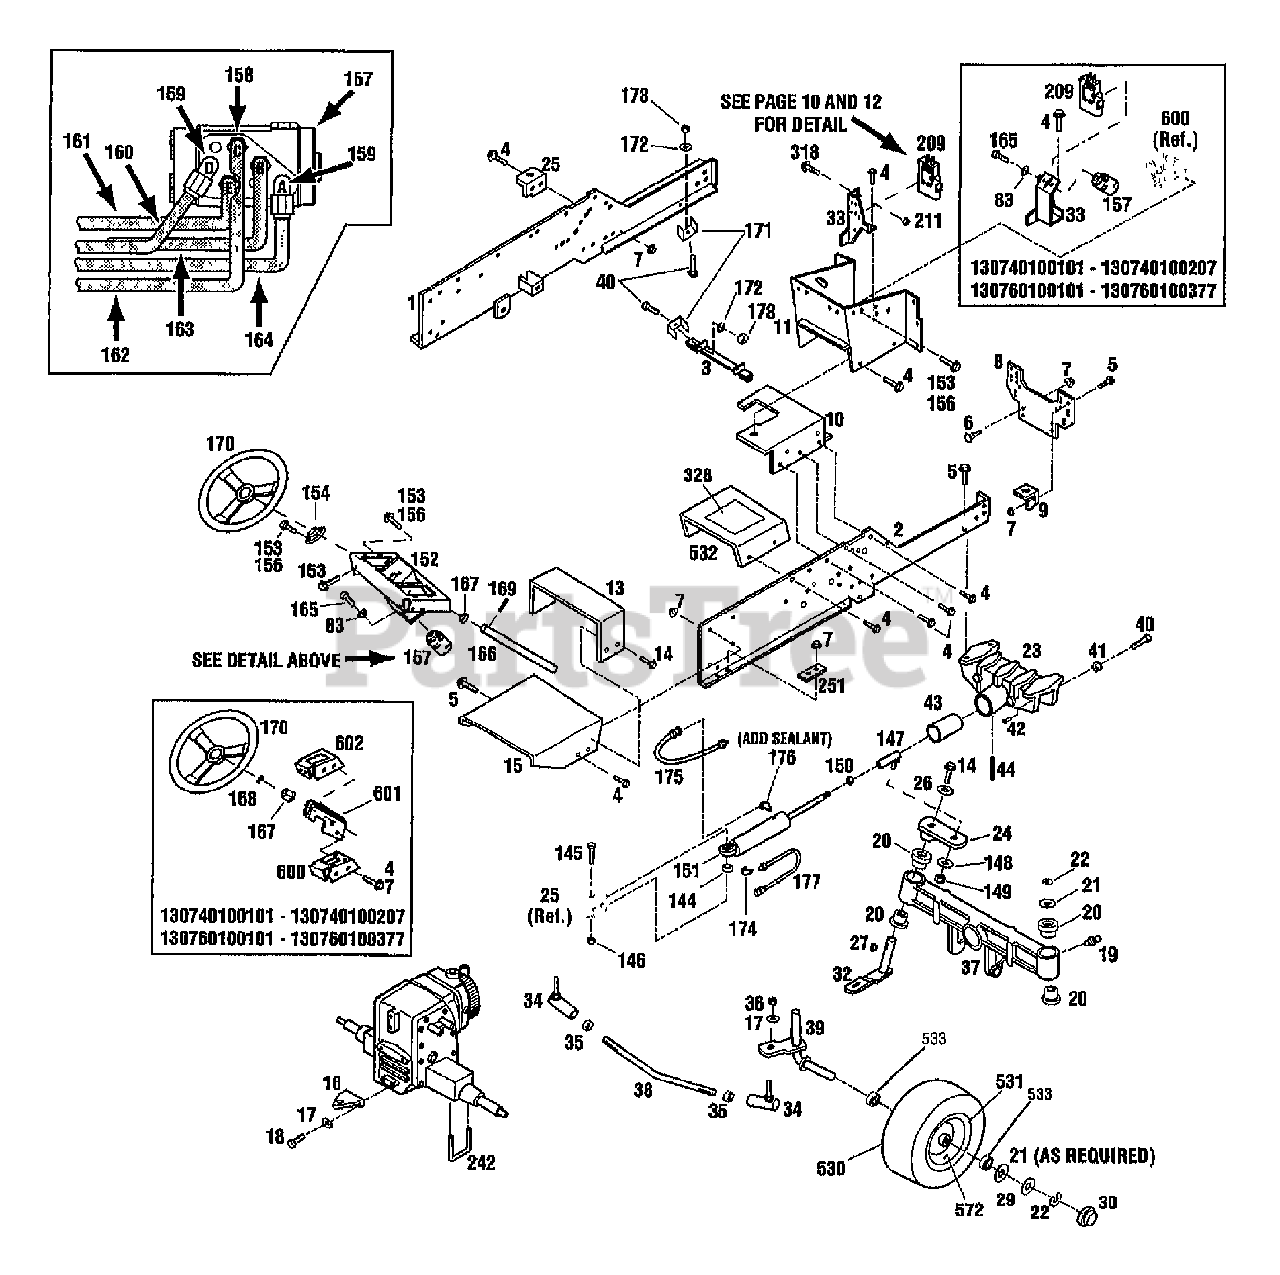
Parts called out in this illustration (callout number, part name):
3	ASSM-FRAME SUPPORT
5	SCR-HFLK 3/8-16X1.00 ZP
6	SCR-CARR 3/8-16X.75 G5 ZP
7	NUT-HFLK 3/8-16 ZP
8	PLATE-FRONT
9	SUPPORT-ENGINE
10	SUPT-BATTERY ASSM
11	SUPPORT
13	SUPPORT-FENDER
14	SCR-HFLK 5/16-18X.75 ZP
15	SUPPORT-FUEL TANK
16	HITCH-DRAWBAR
17	WASHER-LK .5
18	SCR-HH 1/2-13X1.25 G5 ZP
19	FITTING-GREASE 1/4-28X2.00
20	BEARING-FLANGE
21	WASHER-THRUST
22	RING-HEAVY EXT HD 1.0 ID
23	BOLSTER-FRONT AXLE
24	ARM-STEERING
25	BRKT-CYLINDER
26	WASHER-1.75X.328X.1345
27	KEY-WOODRUFF .25X.875
29	WASHER-SPECIAL .75X2.5
30	CAP-HUB
32	SPINDLE-WHEEL LEFT
33	SUPPORT-VALVE
33	SUPPORT ASSM-VALVE
34	JOINT-BALL
35	NUT-JAM
36	NUT-H/LK 1/2-20 ZP
37	AXLE-FRONT
38	ROD-TIE
39	SPINDLE-WHEEL RH
40	SCR-HH 5/16-18X1.0 G5 ZP
41	NUT-HEX JAM 5/16-18
42	PIN-WELD
43	TUBE-PIVOT AXLE
44	PIN-.312X.75
83	WASHER-LK .25 ZP
144	SLEEVE-CYLINDER
145	SCR-HH 5/8-11X3.0 G5
146	NUT-LOCK
147	JOINT-BALL
148	WASHER-LK 1.072X.634X.156
149	NUT-LK TOP 5/18-18
150	NUT-HEX/JAM 5/8-18 ZP
151	CYLINDER-HYDRAULIC
153	SCR-HFLK 5/16-18X.62 G5ZP
154	BRG-FLANGE
156	NUT-HFLK 5/16-18 ZP
157	CONTROL UNIT
158	CONNECTOR
159	ELBOW
160	TUBE-HYD RIGHT
161	TUBE-HYD PB VALVE
162	TUBE-HYDRO PRESSURE
163	TUBE-HYD LEFT
164	TUBE-HYD S C U TANK
165	SCR-HH M6-1.0X19MM
166	SHAFT-STEERING
167	BEARING-FLANGED NYLON
167	COLLAR
168	RING-RET."E".577 ID
169	PIN-DRIVE .25X1.5
170	WHEEL-STEERING
171	CLAMP
172	WASHER-LK .312 ZP
173	NUT-HEX 5/16-18 ZP
174	ELBOW
175	ASSM-HOSE
176	ELBOW
177	ASSM-HOSE
209	VALVE-HYDRAULIC
211	NUT-HF/LK 1/4-20 ZP
242	BOLT-U
251	DOUBLER-FRAME REAR
318	SCR-HH 1/4-20X.625
328	DECAL-OPERATING INST
530	TIRE-16X6.50-8
531	WHEEL
532	TUNNEL W/DECAL
533	BEARING-BALL
572	STEM-VALVE
600	BRKT-STEERING
601	SUPPORT-STEERING
602	STEERING BRACKET
